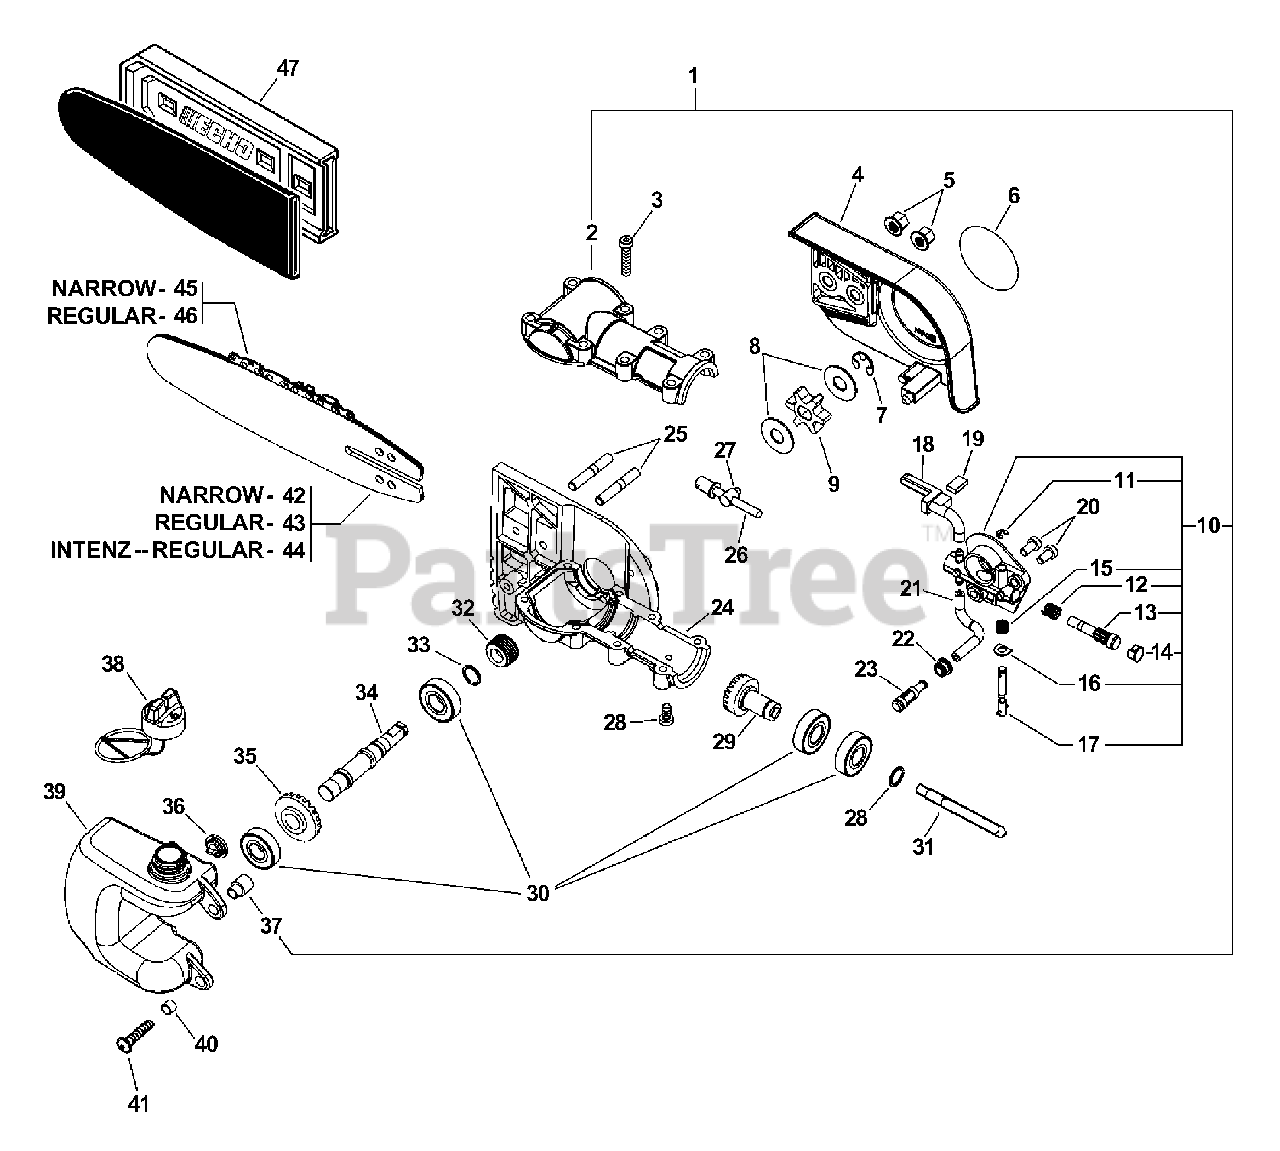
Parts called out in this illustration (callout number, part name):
1	OILER/GEAR CASE ASSY
2	CASE, GEAR - UPPER
3	SCREW - 5X25
4	GUARD, SPROCKET
5	NUT - 6 -- FLANGE
6	LABEL - ECHO
7	RING, RETAINING
9	SPROCKET, DRIVE
10	AUTO-OILER ASSY
11	RING, RETAINING
12	SPRING, PLUNGER
13	PLUNGER ASSY
14	CAP, OIL PUMP
17	NEEDLE, ADJUST
18	PIPE, OIL OUTLET
19	PAD, FOAM
20	SCREW - 5X10
21	PIPE - 3X6X75 -- BLACK
22	GROMMET
23	FILTER, OIL
24	CASE, GEAR - LOWER
25	STUD - 6
26	SCREW, TENSIONER
27	TENSIONER, CHAIN
28	RING, RETAINING - 12
29	GEAR - BEVEL
30	BEARING, BALL - 6001
31	CONNECTOR, SHAFT
32	GEAR - WORM
33	RING, RETAINING - 12
34	GEAR - SHAFT
35	GEAR - BEVEL
38	CAP ASSY
39	TANK, OIL
41	SCREW - 5X20
42	GUIDE BAR - 10" (25cm)
43	GUIDE BAR - 10" (25cm)
44	GUIDE BAR - 10" (25cm) Intenz
45	SAW CHAIN - 10" (25cm)
46	SAW CHAIN - 10" (25cm)
47	COVER, GUIDE BAR
